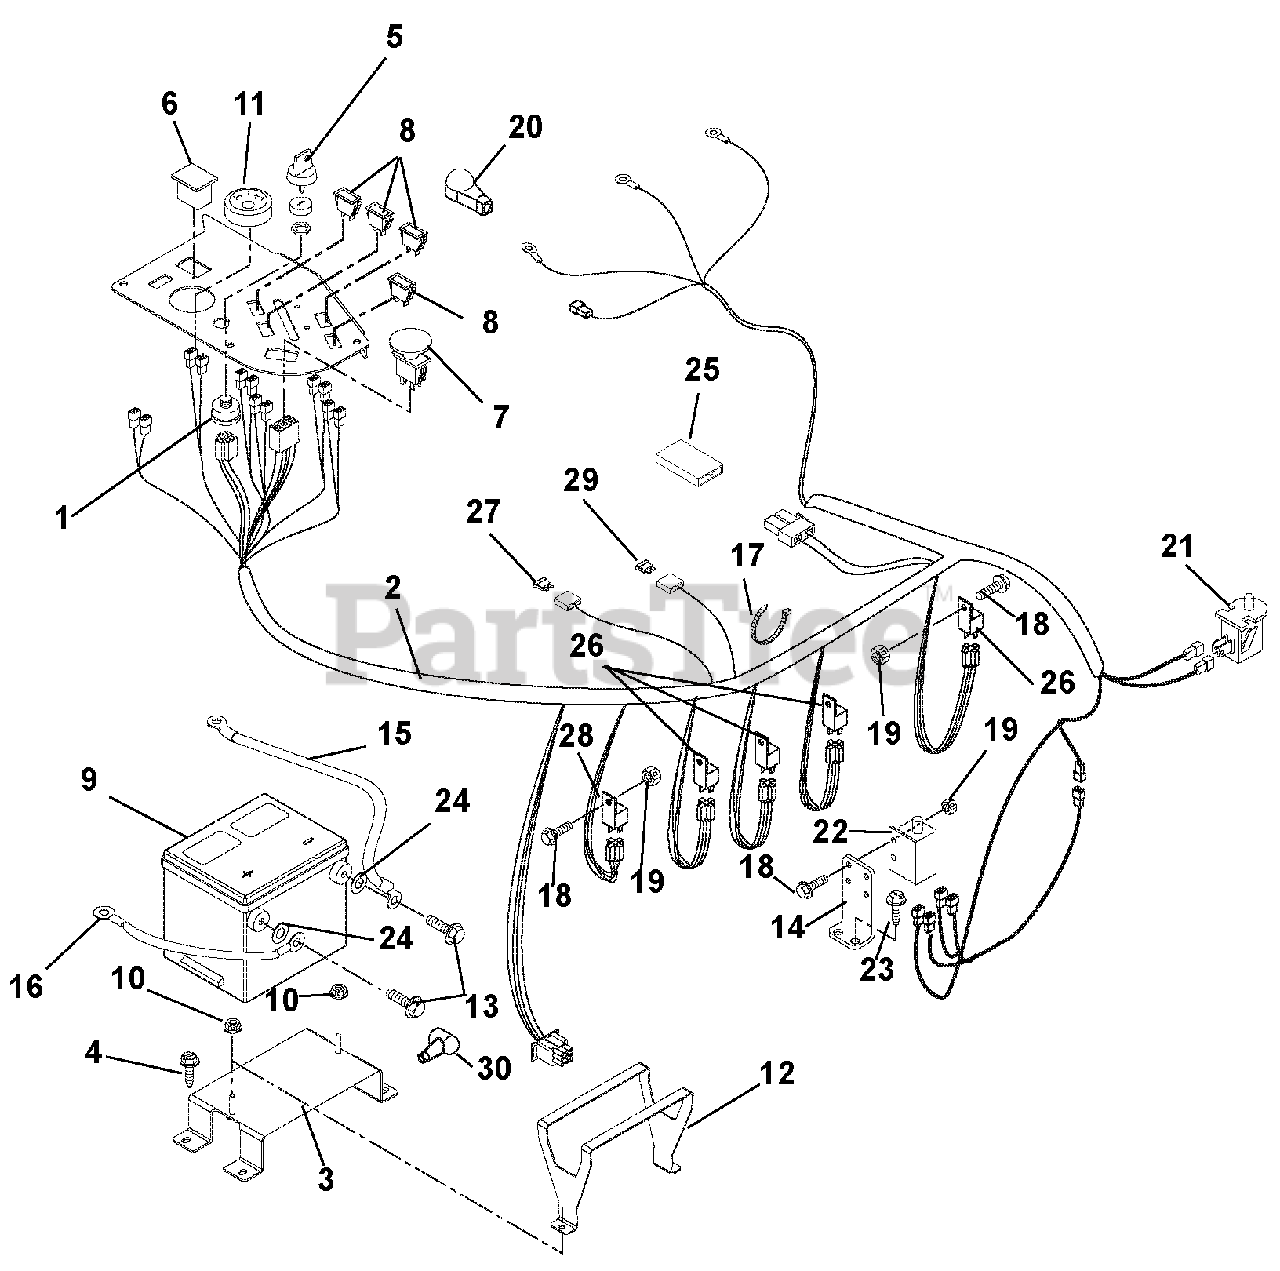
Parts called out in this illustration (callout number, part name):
1	Switch, Ignition
2	Harness, Wiring
3	Weldment, Battery Support
4	Screw, Tapping Hex Washer Head .38-16 x .75
5	Key, with Cap
6	Hour Meter with Maintenance
7	Switch, Clutch with Retainer Ring
8	Light, Indicator
10	Nut, Locking Top Flange .31-18
11	Gauge, Temperature
12	Bracket, Battery Hold-Down
13	Bolt, Hex .25-20 x .75 Grade 5
14	Mount, Safety Switch
15	Cable, Positive Battery with Boots
16	Cable, Negative Battery
17	Cable Tie
18	Screw, Machine Hex Washer Head 10-24 x .75
19	Nut, Locking Nylon 10-24 with Insert
20	Boot Terminal, Red (Included with Cable)
21	Switch, Snap Mounting (N.O.) (Included with Seat)
22	Switch, Single Pole (Brake)
23	Screw, Tapping Hex Washer Head .25-20 x .50
24	Washer, Flat Steel .406 x 1.00 x .083
25	Diode, Connector Shell
26	Relay (Included with Harness)
27	Fuse, ATO 30 Amp (Included with Harness)
28	Pre-Heat Timer (Included with Engine)
29	Fuse, ATO 60 Amp (Included with Harness)
30	Battery Terminal Boot, Red (Included with Cable)
